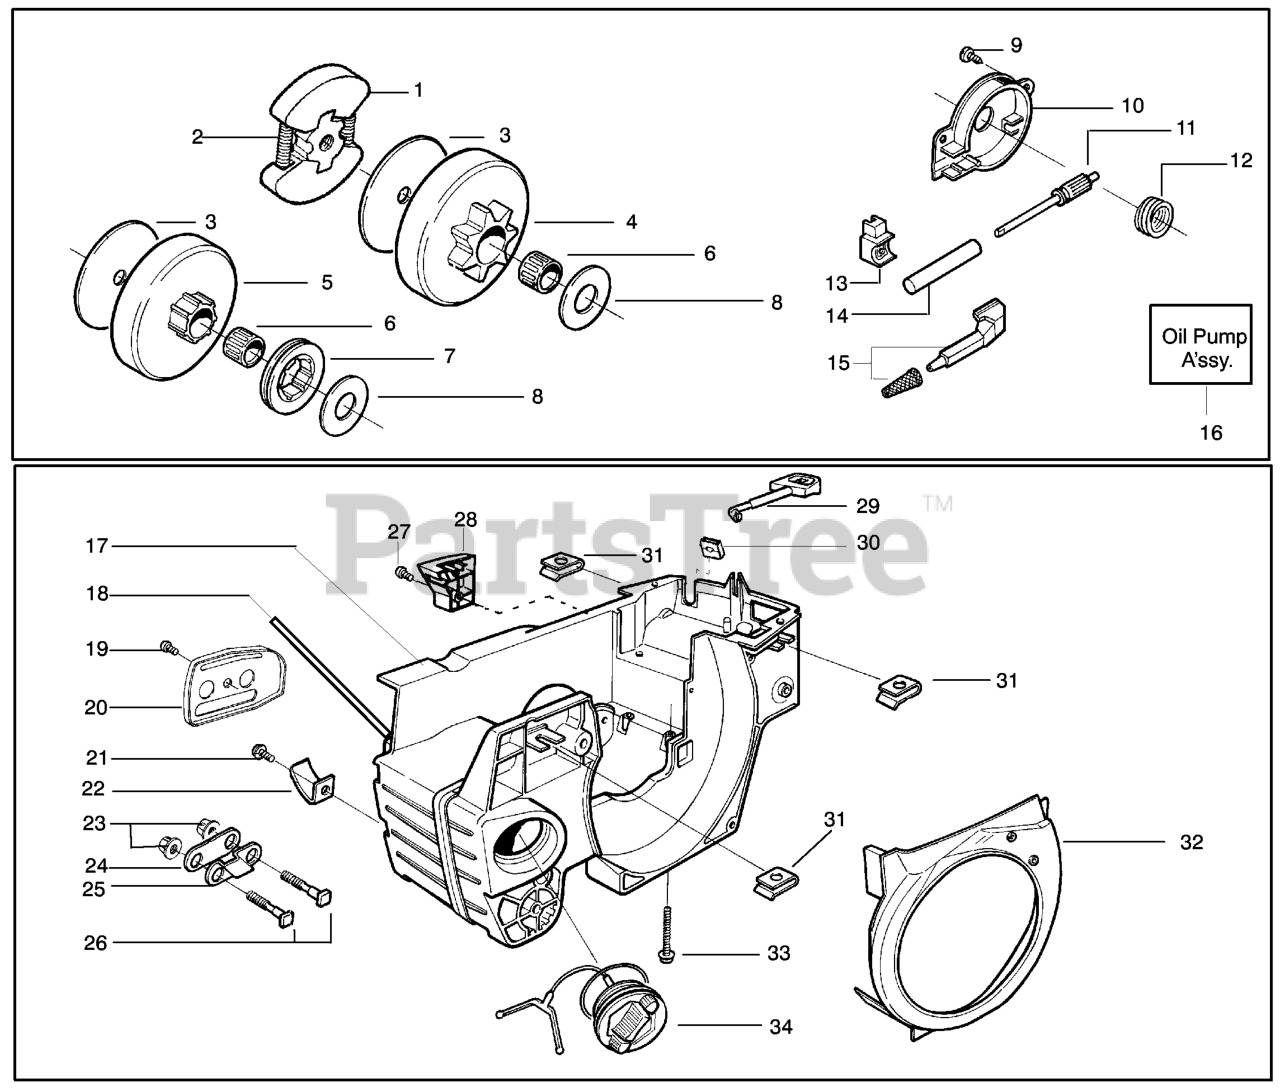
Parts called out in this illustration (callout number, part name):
1	CLUTCH ASSEMBLY
2	CLUTCH SPRING 36/41
3	FRICTION DISC,CLUTCH 36/41
4	CLUTCH DRUM ASSY
5	CLUTCH DRUM 325 X 7T
6	NEEDLE BEARINGS 36/41
7	RIM .325 7T 36/41
8	THRUST WASHER
10	OIL PUMP HOUSING
11	PLUNGER & GEAR ASSEMBLY
12	OILER GEAR 36/41
13	PRESSURE SEAL,OILER 36/41
14	OIL PUMP BARREL
15	OIL PICKUP
16	OILER ASS'Y 36/41
17	CRANKCASE ASSY
18	TUBE
19	SCREW
22	CHAIN CATCHER 36/41
24	OIL TANK GASKET
25	PLATE,BAR MOUNT
26	BAR BOLT 36/41
28	LIMITER COVER
29	CHOKE 36/41
30	CHOKE GUIDE 36/41
32	AIR CONDUCTOR 36/41
33	SCREW M5-0.8X35M TAP
